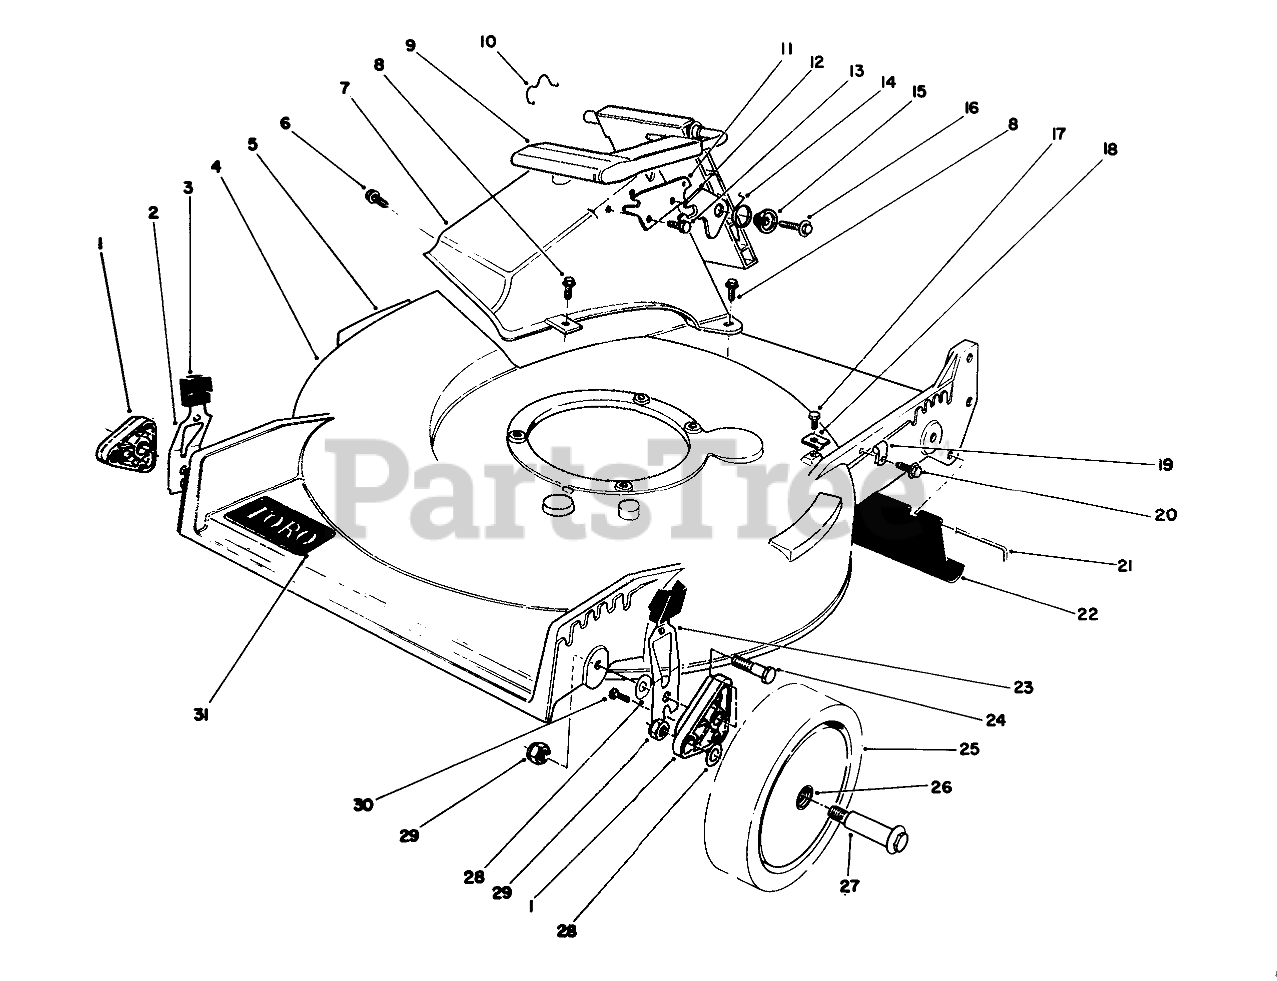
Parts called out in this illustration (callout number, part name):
1	ARM-PIVOT, FRONT
2	RH SPRING ARM ASSEMBLY
3	KNOB-ARM
4	Housing (Incl. Ref. #5)
5	DECAL-DANGER
6	SCREW AND WASHER ASM
7	Tunnel Discharge
8	SCREW-HWH
9	Discharge Door Assembly
10	DOOR RET SPRING
11	DOOR LATCH PLATE
12	SAFETY LATCH
13	SCREW-PLASTITE
14	TORSION SPRING
15	DOOR SPACER
16	SCREW-HWH
17	SCREW-HWHTF
18	CLAMP-CABLE
19	CLAMP-CABLE
20	SCREW
21	ROD-SHIELD
22	SHIELD-TRAILING
23	LH SPRING ARM ASSEMBLY
24	BOLT-SHOULDER
25	Wheel & Tire Assembly (Incl. Ref. #26)
26	BUSHING
27	WHEEL BOLT
28	WASHER
29	Nut
30	SCREW-HWH
31	DECAL
